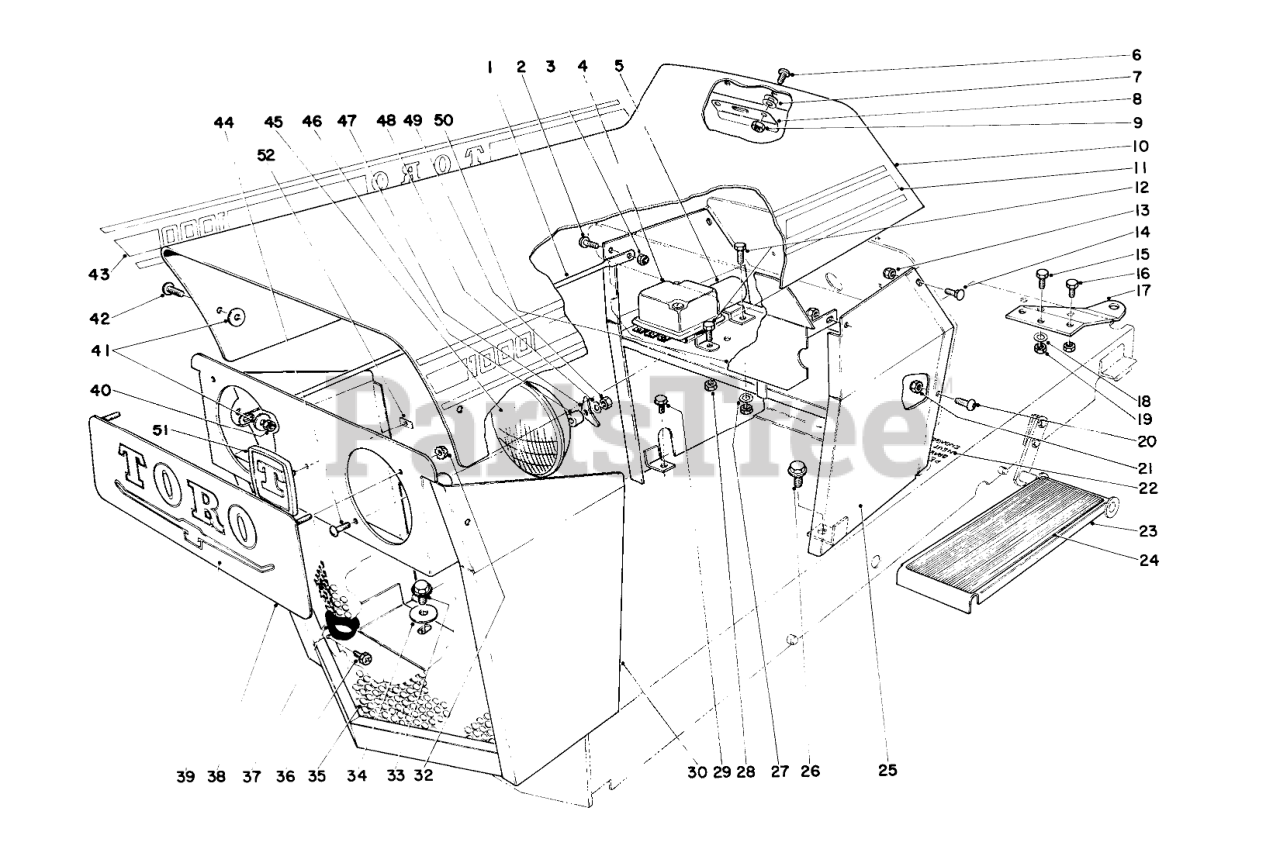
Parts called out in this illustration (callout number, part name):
1	Rod Hood Support
2	SCREW-HSBH
3	NUT-LOCK, CONE
4	Voltage Regulator
5	Solenoid
6	Screw, Machine
7	WASHER-FLAT
8	Hood Latch
9	NUT-LOCK, CONE
11	Decal Side L.H. 10 H.P.
12	SCREW-HH
13	NUT-LOCK, CONE
14	SCREW-CARR
15	SCREW-HH
16	SCREW-HH
17	Chassis Hitch
18	WASHER-FLAT
19	NUT-LOCK, CONE
20	SCREW-HSBH
21	NUT-LOCK, CONE
22	Decal Clutch Release
23	Foot Rest
24	Pad Foot Rest
25	Battery Support
26	5/16-18 X 5/8 SEMS SC
27	WASHER-FLAT
28	NUT-LOCK, CONE
29	Screw-HH
30	Grille Frame W.A.
32	NUT-KEPS
33	5/16-18 X 5/8 SEMS SC
34	Washer
35	Grille
37	Grommet
38	Head Light Cover
39	Decal Cover Plate
40	NUT-LOCK, CONE
41	Washer
42	SCREW-HSBH
43	Side Hood R. H. 10 H.P.
44	SCREW-SRH
45	HEAD LAMP
46	Spacer
47	Clip 960
48	WASHER-LOCK/SP
49	NUT-HEX
50	Heat Deflector
51	Logo Plate Recoil
52	Timmerman Nut
